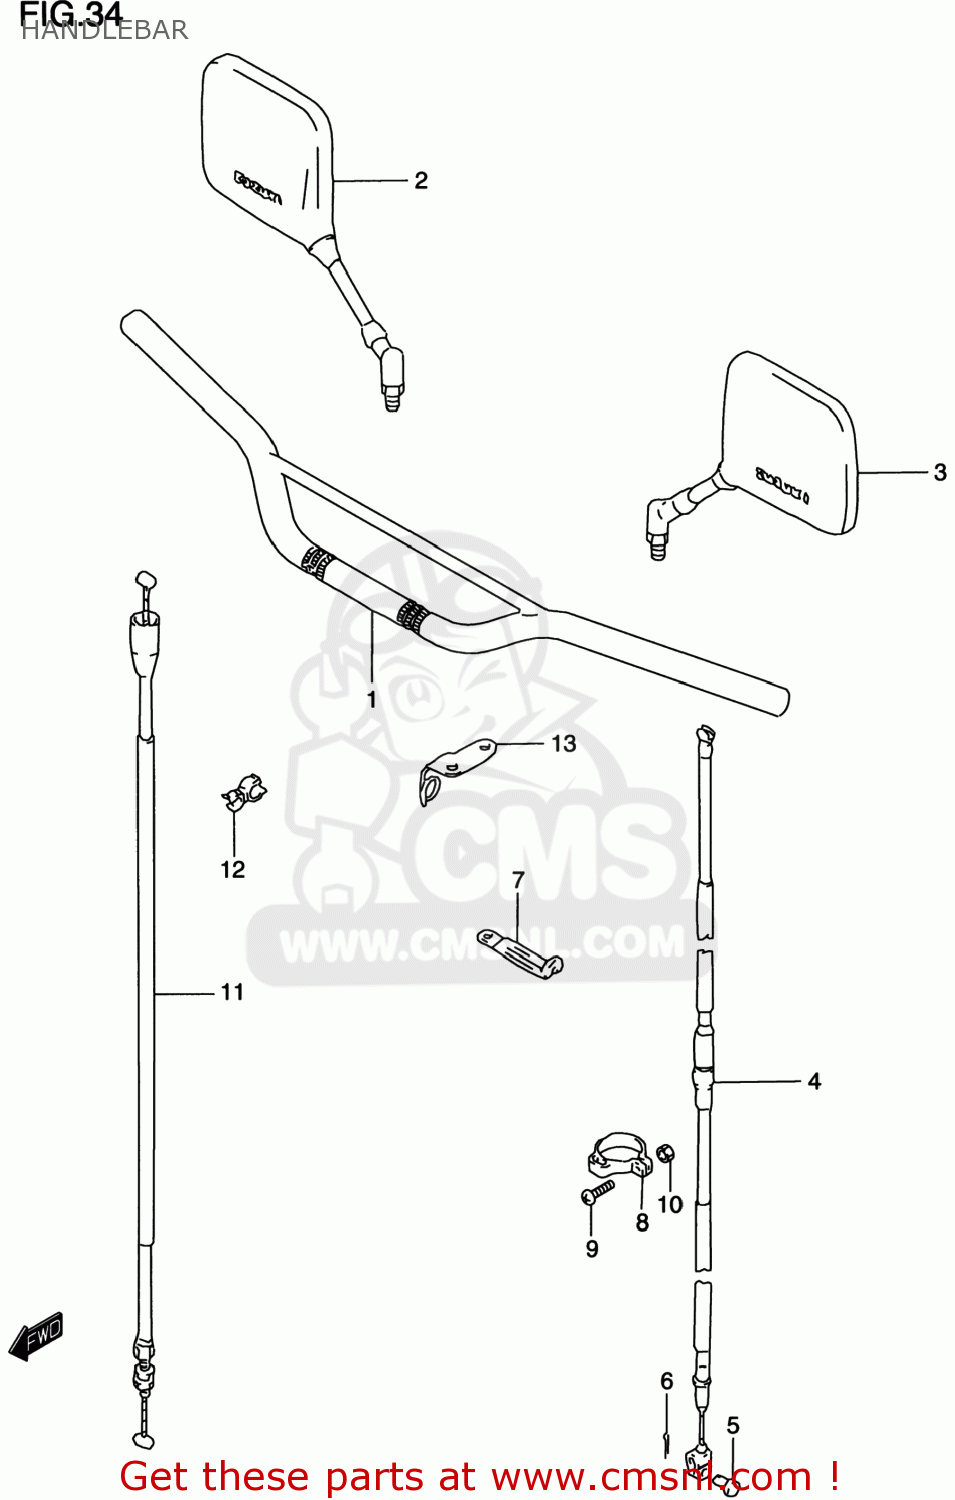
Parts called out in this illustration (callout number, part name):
1	HANDLEBAR(BLACK)
2	MIRROR ASSEMBLY,RIGHT
3	MIRROR ASSEMBLY,LEFT
4	CABLE ASSY,CLUTCH
5	PIN(L:13)
6	PIN
7	CLAMP(L:235)
8	CLAMP,CABLE
9	SCREW
10	NUT
11	CABLE ASSY,THROTTLE
12	CLAMP
13	GUIDE,CABLE
